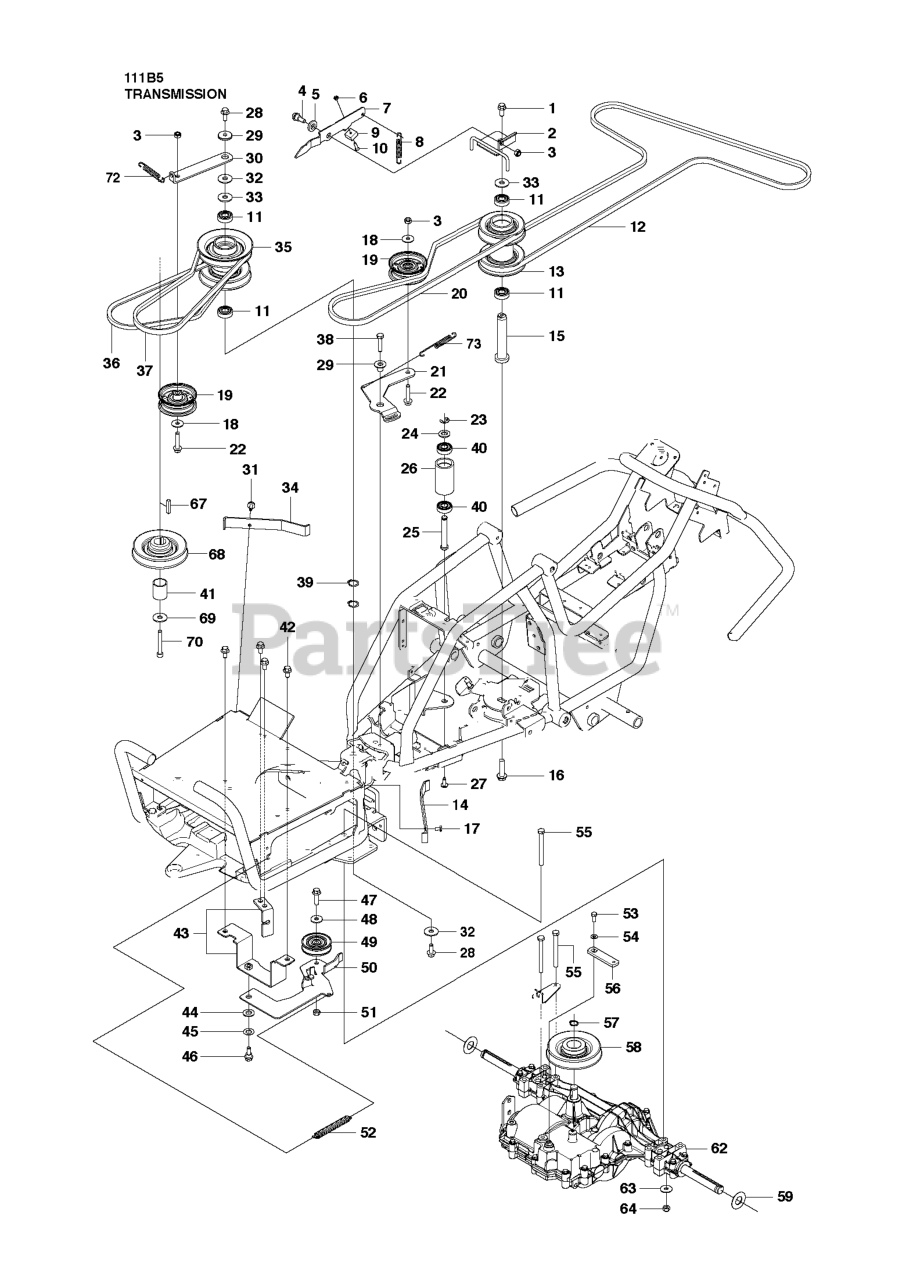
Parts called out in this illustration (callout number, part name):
3	LOCKNUT M8
6	LOCKNUT M5
11	BALL BEARING 6004-2RS1
19	IDLER PULLEY
21	BELT TENSIONER
23	RETAINING RING
24	WASHER - M12
28	BOLT
29	WASHER
38	BOLT
39	RETAINING RING SGA 20
40	BALL BEARING 6201-2RS1
44	WASHER - M12
45	SPRINGWASHER
47	SCREW
51	LOCKNUT M8
54	WASHER
57	Retaining Ring Sga 16
63	WASHER BRB 8.4X17
64	NUT
